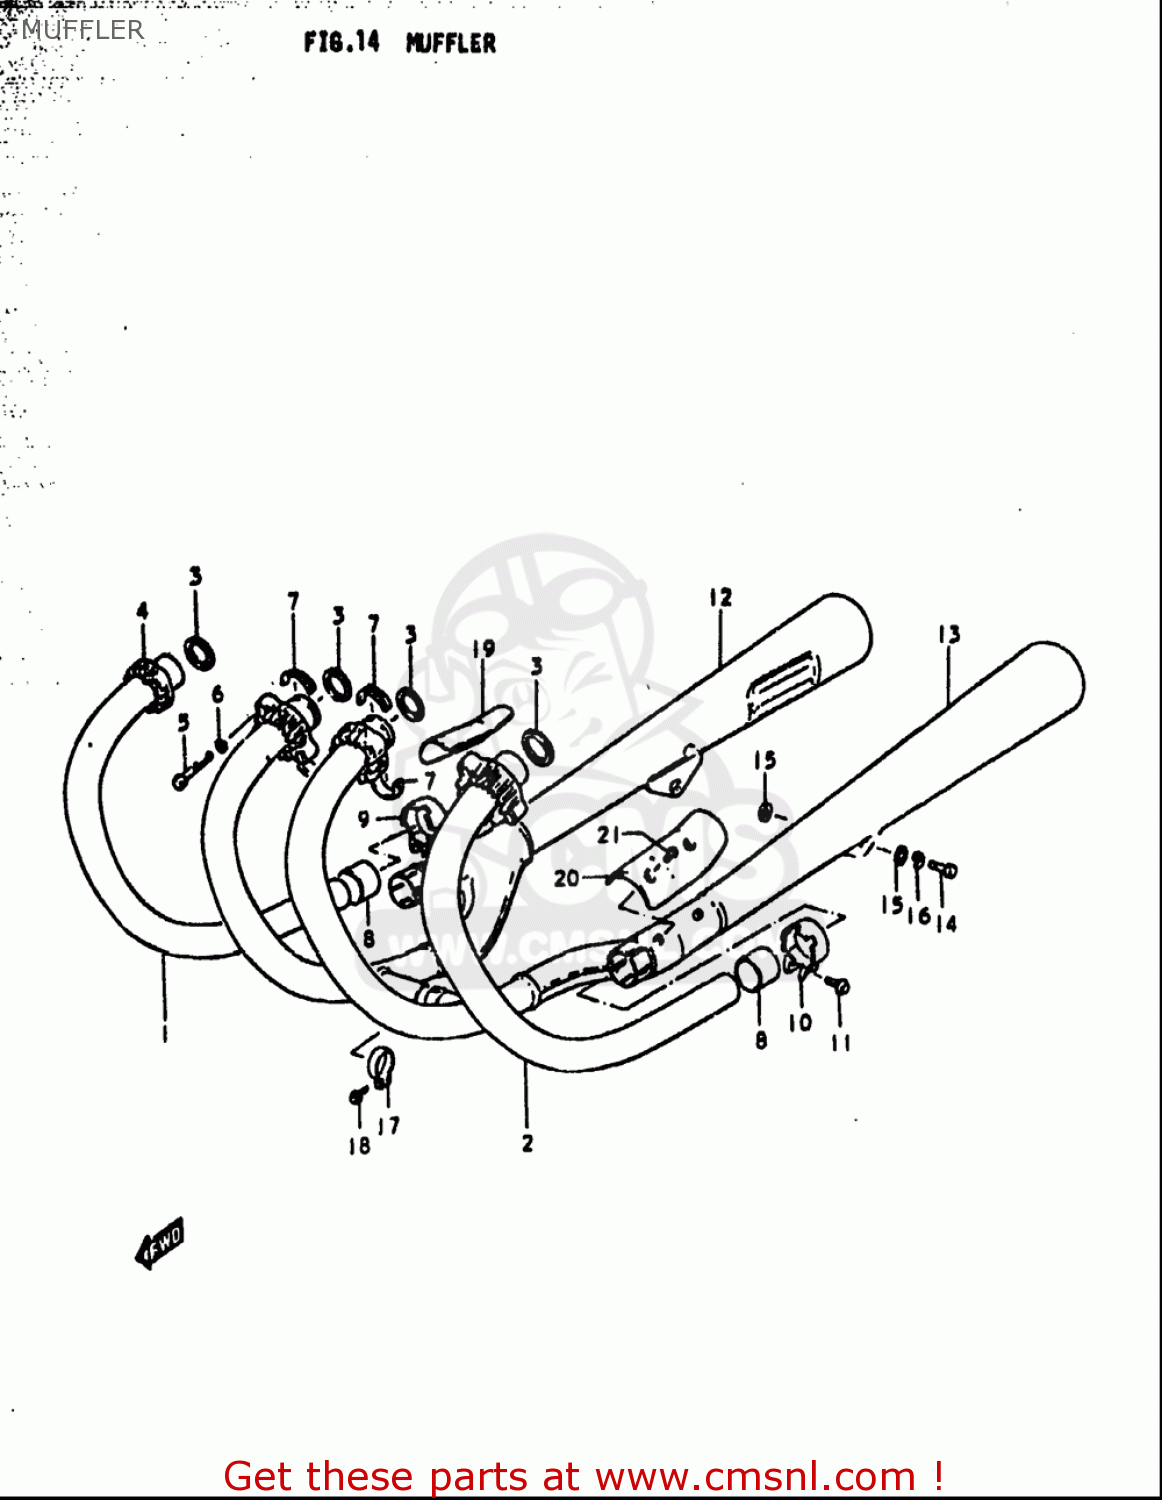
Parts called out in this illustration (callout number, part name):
1	PIPE,EXHAUST,R
2	PIPE,EXHAUST,L
3	GASKET,EXHAUST PIPE (NAS)
4	CLAMP,EXHAUST PIPE
5	BOLT
6	WASHER,LOCK
7	PLATE,EXHAUST P
8	CONNECTOR,MUFFLER
9	CLAMP,MUFFLER CONNECTOR,R
10	CLAMP,MUFFLER CONNECTOR,L
11	BOLT
12	MUFFLER ASSEMBLY,RIGHT
13	MUFFLER ASSEMBLY,LEFT
14	BOLT
15	WASHER
16	WASHER,LOCK
17	CLAMP
18	BOLT
21	SCREW(5X6)
